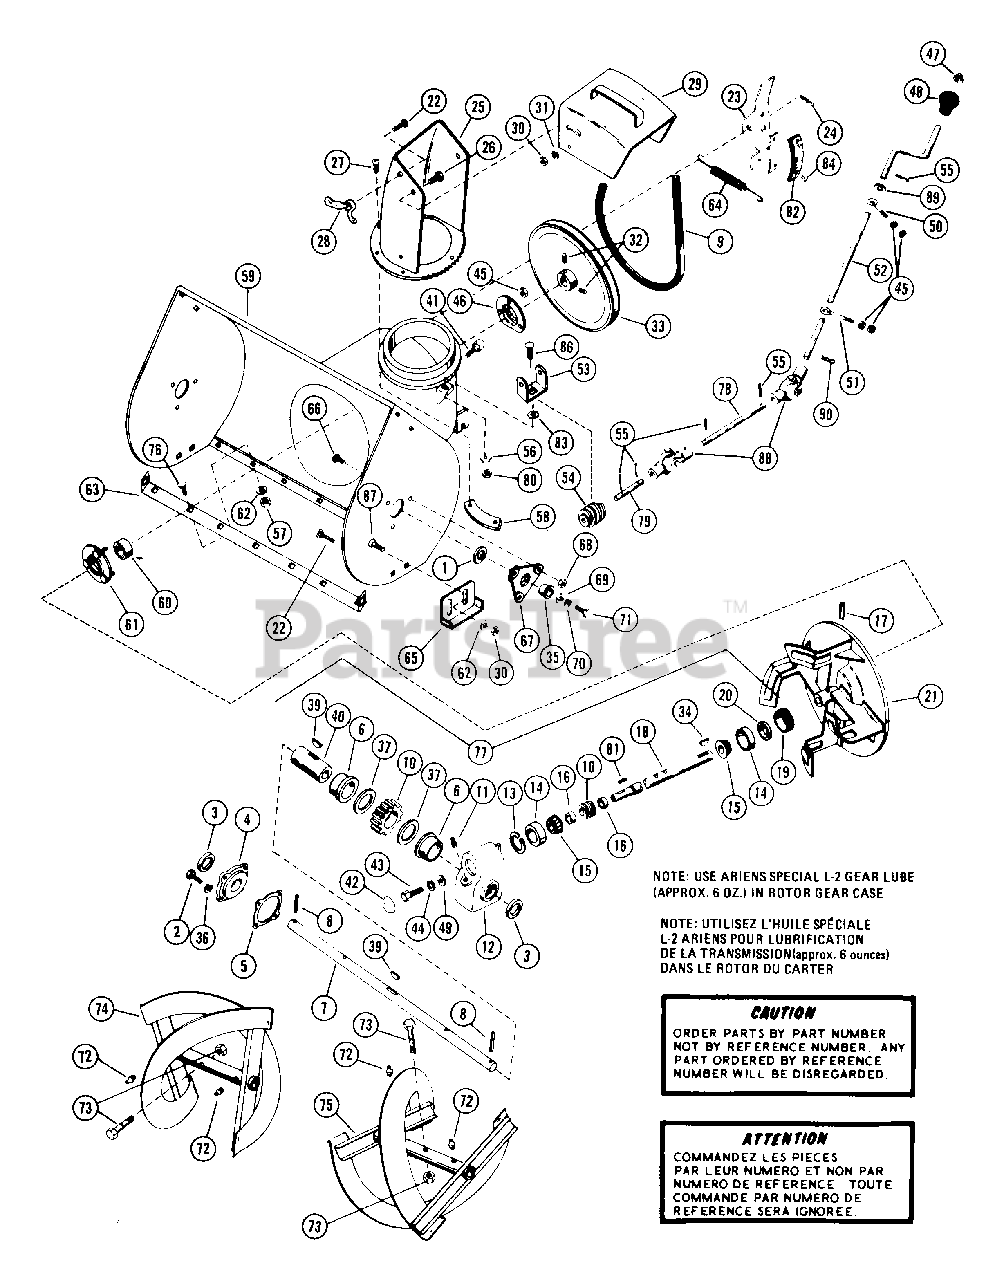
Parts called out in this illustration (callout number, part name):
1	WSHR-FL-STL 1.010X1.505X.062PL
2	BLT-HEX .25-20X.75 PL GR2
3	SEAL 1.625X2.125X.250
4	GEAR CASE COVER
6	BSHG-FLG .683X1.87X1.68X2.250
7	SHAFT, 32" RAKE - 1.00 DIA.
8	PIN-ROLL .188X1.50
10	WORM & GEAR SERVICE ASSEMBLY
11	PIPE PLUG
12	GEAR CASE - CAST IRON
13	RG-RTNG INT 1.781 HSG X.062
14	BRG-CUP 1.781X.475
15	BRG-CONE .750X.61
16	BSHG, SPCR .755X1.12X.50 PM
17	PIN-ROLL .313X1.75
18	SHAFT, WORM - 1.00 DIA.
19	ADJUSTMENT PLUG - 1" SHAFT
20	SEAL 1.000X1.312X.150
21	FAN, 12"
22	BLT-RDHDSQNK .38-16X.75 SHT PL
23	BRAKE ARM ASSEMBLY
24	PIN-COTR .12X1.0 PL
25	CHUTE - DISCHARGE
26	BLT-HEX .38-16X.75 PL GR2
27	SCR-TAP 10-24X.375 HWH PL TR
28	WING NUT
29	SERVICE DEFLECTOR ASSM
30	NUT-LK-CTR .375-16 GR A PL
31	WSHR-LK .375X.115 HVY PL
32	SCR-SET .32-18X.38 SKHCUPNL OH
33	PLY-? 9.0X.75
34	KEY-WDRF .188X.875X.375 SAE11
35	BSHG-FLG 1.000X1.12X.62X1.50BR
36	WSHR-LK-EXT. 250 ID
37	WSHR-FL-STL 1.625X2.500X.012
39	KEY-WDRF .25X.875X.375 SAE A
40	GEAR CASE SHAFT
41	BLT-SCRHFWH .38-16X.75 PL
42	DUST CAP
43	BLT-HEX .31-18X.75 PL GR2
44	WSHR-LK .312X.097 PL HVY
45	NUT-LK-CTR .250-20 PL
46	BEARING FLANGE
47	CAP, 3/8 ROD YWZC
49	WSHR-FL-STL .328X1.0X.094
50	ROD HANGER EYEBOLT
51	EYEBOLT
52	CHUTE CONTROL CRANK
53	WORM CLEVIS
54	WORM GEAR
55	PIN-ROLL .125X.75
56	WSHR-LK .313X.062
57	NUT-LK .312-18 GR A PL
58	CHUTE CLAMP
59	32 IN BLOWER HOUSING ASSY
60	BRG-BALL .750X1.750X.50
61	BEARING FLANGE
62	WSHR-FL-STL .38X.875X.083 PL
63	SCRAPER BLADE
64	SG-TENS .062X.56X8.0 WLD 11
65	RUNNER
66	SCR-SLTR-SERNK .25-20X.62 PL
67	BEARING SUPPORT
68	NUT-LK-FLG .250-20 PL
69	WSHR-FL-STL .511X1.441X.125 PL
70	WSHR-LK .500X.151 HVY PL
71	BLT-HEX .50-13X1.00 PL GR2
72	SPIN DRIVE ZERK FITTING
73	SHEAR BOLT SERVICE ASSEMBLY
74	RAKE, RIGHT-32"(1ID X 15.75OD)
75	RAKE, LEFT-32"(1"ID X 15.75OD)
76	BLT-RDHDSQNK .312-18X.62 PL
77	GEAR CASE - CAST IRON
79	WORM SHAFT
80	NUT-HEX .312-18
81	KEY-SQ .188X1.0X.188 SAE 8630
82	BRAKE LINING
83	WSHR-LK-EXT .313X.030 PL
84	RVT-TBLR .187X.375 OH ST PL
86	BLT-RDHDSQNK .31-18X.75 GR5 PL
87	BLT-RDHDSQSHNK .38-16X1.00 PL
88	UNIVERSAL JOINT ASSEMBLY
89	WSHR-FL-STL.406X.812X.065PL
90	PIN-HAIR INT .08X.38X1.42 YWZC
